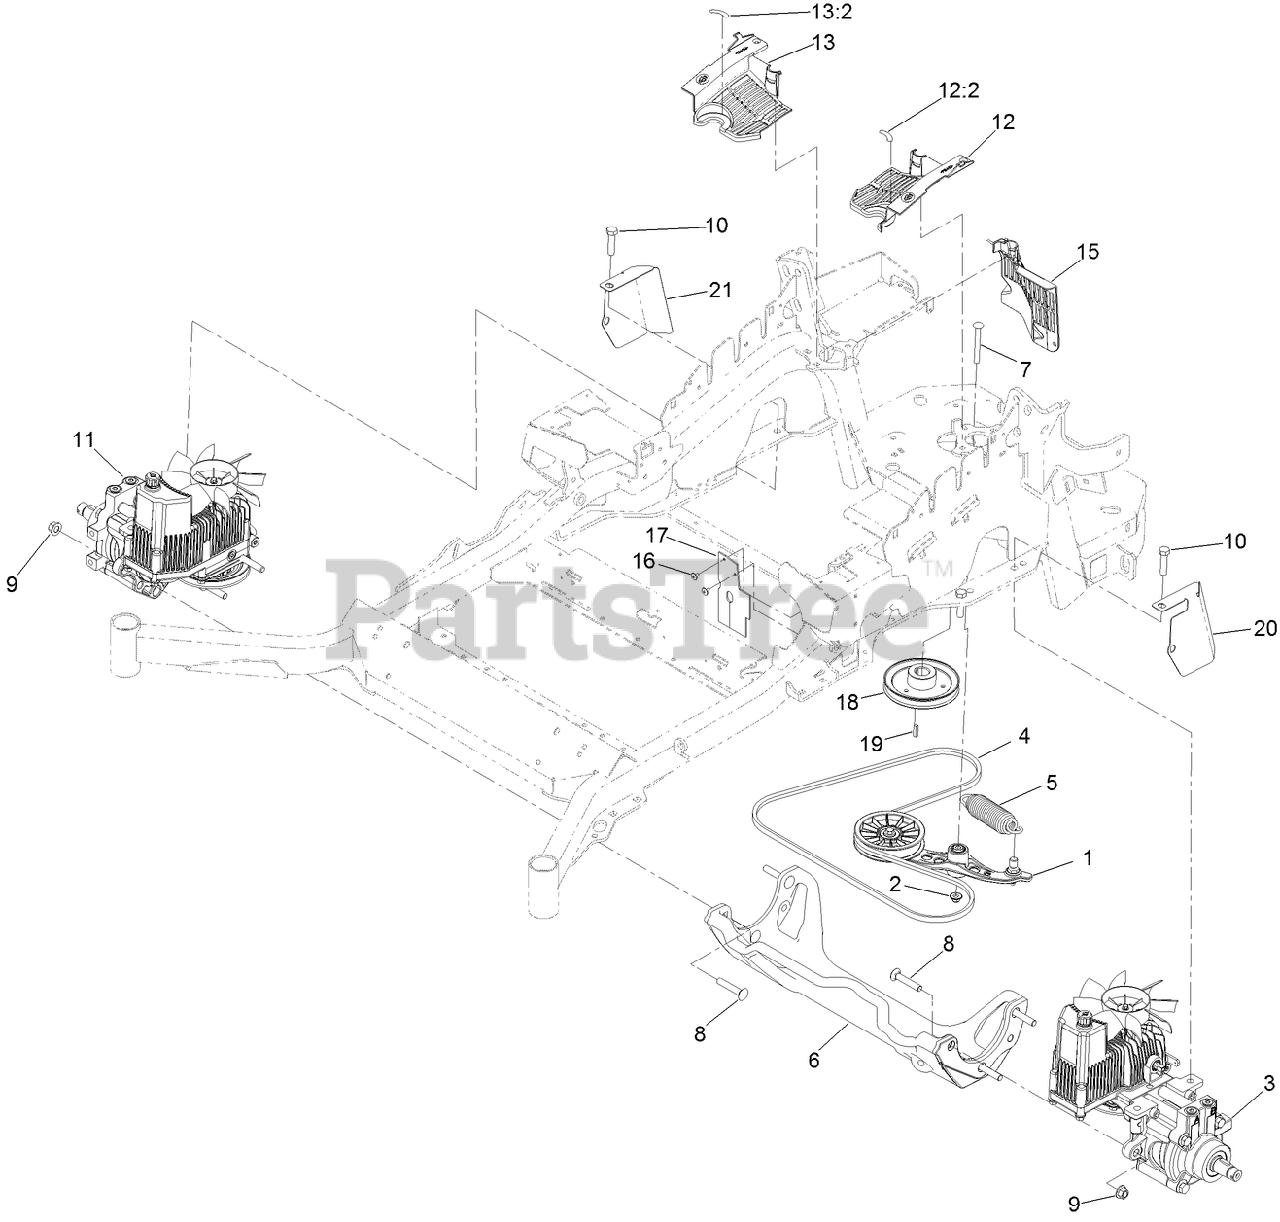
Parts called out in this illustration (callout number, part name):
1	PUMP IDLER ASM
2	NUT-FLANGE, NI
3	LH HYDRO ASM (16CC W/ SHOCK)
4	BELT
5	SPRING-EXTENSION
6	CRADLE-HYDRO
7	BOLT-SHOULDER, CARRIAGE
8	SCREW-CARR
9	NUT-LOCK
10	SCREW-HH
11	RH HYDRO ASM (16CC W/ SHOCK)
12	LH HYDRO GUARD ASM
12:2	DECAL-OIL, HYDRO
13	RH HYDRO GUARD ASM
13:2	DECAL-OIL, HYDRO
15	GUARD-HYDRO, REAR (RH)
16	RIVET-POP
17	DEFLECTOR-AIR FLOW
18	SHEAVE
20	GUARD, LH REAR [BLACK]
21	GUARD, RH REAR [BLACK]
